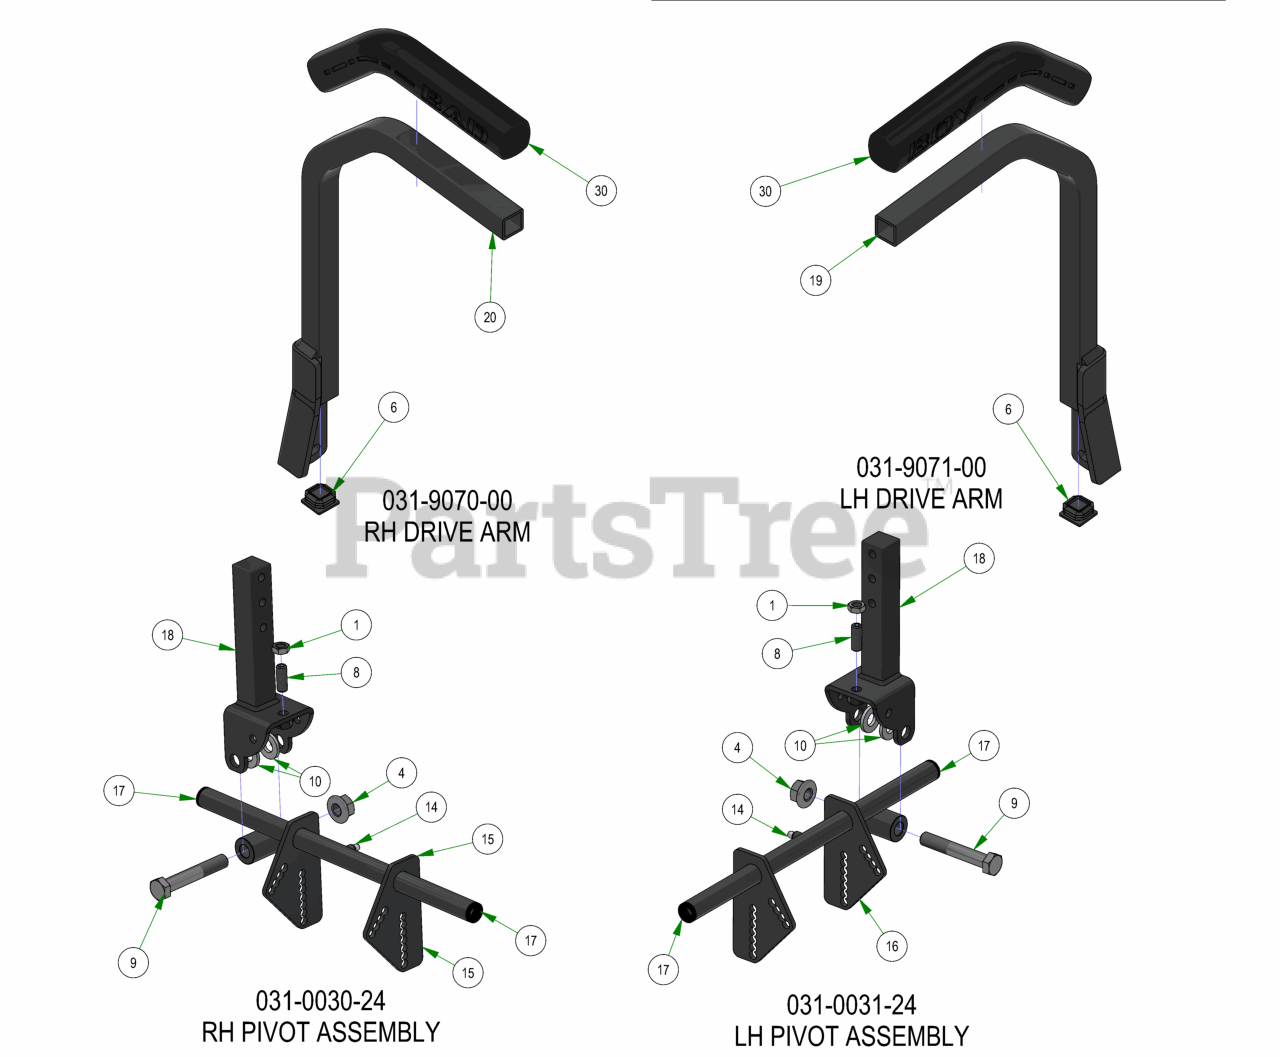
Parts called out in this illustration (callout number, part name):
1	3/8-16 Half Jam Nut
2	5/16" RH Fine Threaded Jam Nut
3	5/16" LH Fine Threaded Jam Nut
4	1/2-13 NYLON INSERT FLANGE LOCKNUT ZINC
5	Fan Guard 6" - Fits Wheel
6	9565K52_Polyethylene Square Plug
7	Hydro Fan - Light/Pup/Outlaw XP
8	3/8-16 X 1 SOCKET SET SCREW (CUP POINT) PLAIN
9	1/2-13 X 3 HEX CAP SCREW (GR.5) ZINC
10	.505 ID X 1.000 OD X .125 THICK FLAT WASHER NYLON
11	ZT Fitting, 3/8 x 3/8 45 Degree, 4603-6-6
12	2019 Outlaw 45 Degree Pump Fitting #6802-10-08
13	90 Degree Fitting, 1/2 x 3/4, 4601-8-8
14	1/4" Press in Grease Fitting
15	2019 Drive Arm Actuator right - Weldment
16	2019 Drive Arm Actuator left - Weldment
17	2019 Drive Arm Bushing
18	R Series Square Drive Arm Pivot
19	R Series Square Drive Arm LH Weldment
20	R Series Square Drive Arm RH Weldment
21	2019 Outlaw Gen2 Xp Rod
22	Spherical Rod End - Outlaw
23	Spherical Rod End - Outlaw
24	3/8" Clear Hose x 4 1/2"
25	1/2 Clear Braded Hose Priced/Foot x 9.5"
26	Hydraulic Filter
27	Hydraulic Tank Cap W/Dipstick
28	2019 Left Outlaw Gen2 Hydro Tank Suspension Only
29	2019 Right Outlaw Gen2 Hydro Tank Suspension Only
30	R-Series Square Drive Grip
31	3/8" Hose Clamp
32	1/2 Hose Clamp
